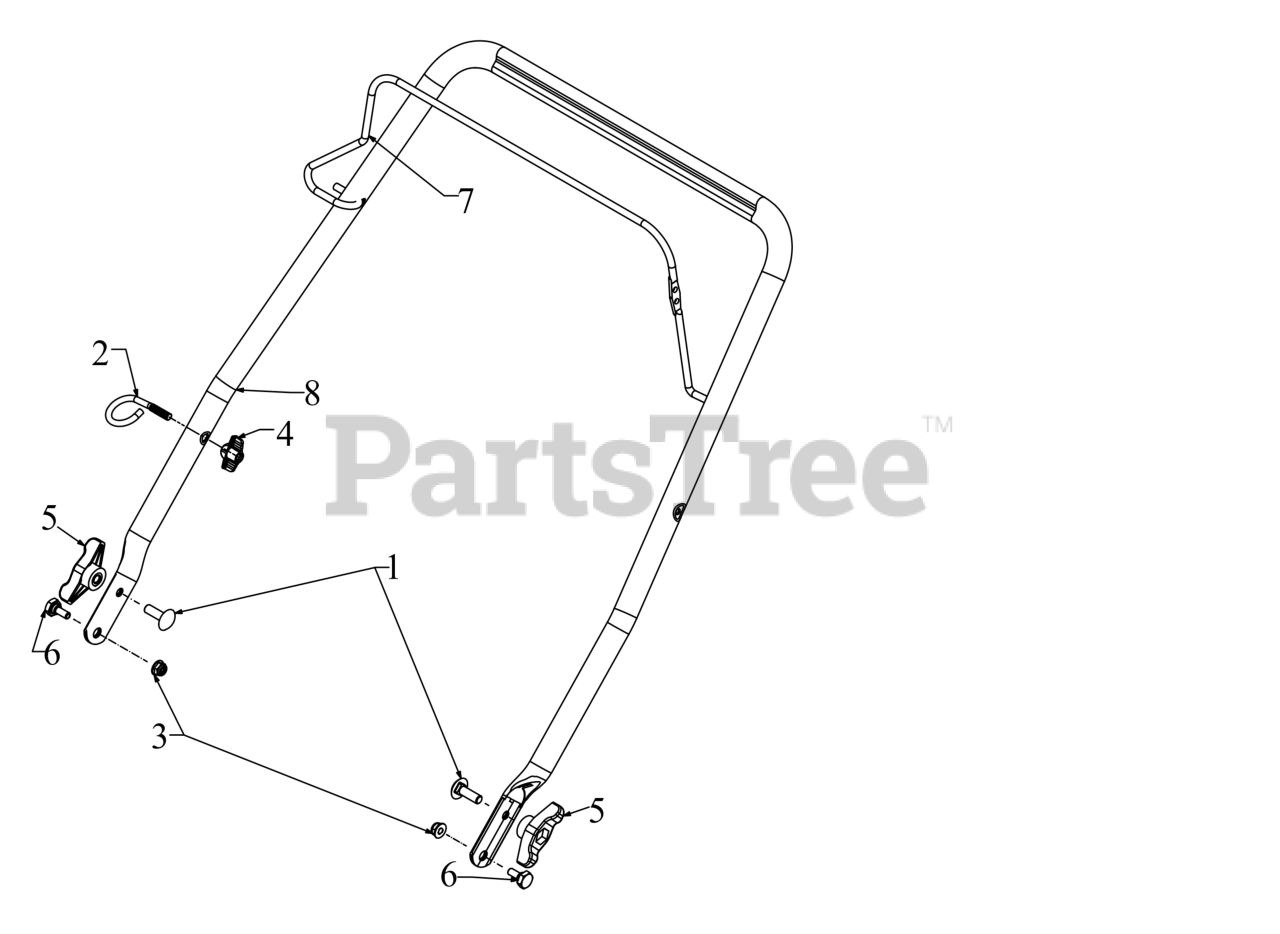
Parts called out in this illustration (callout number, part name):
1	SCREW 5/16-18 x 1.00 GR5
2	EYEBOLT 1/4-20
3	FLANGE LOCK NUT
4	HANDLE KNOB
5	WING KNOB 5/16-18
6	SHOULDER SCREW
